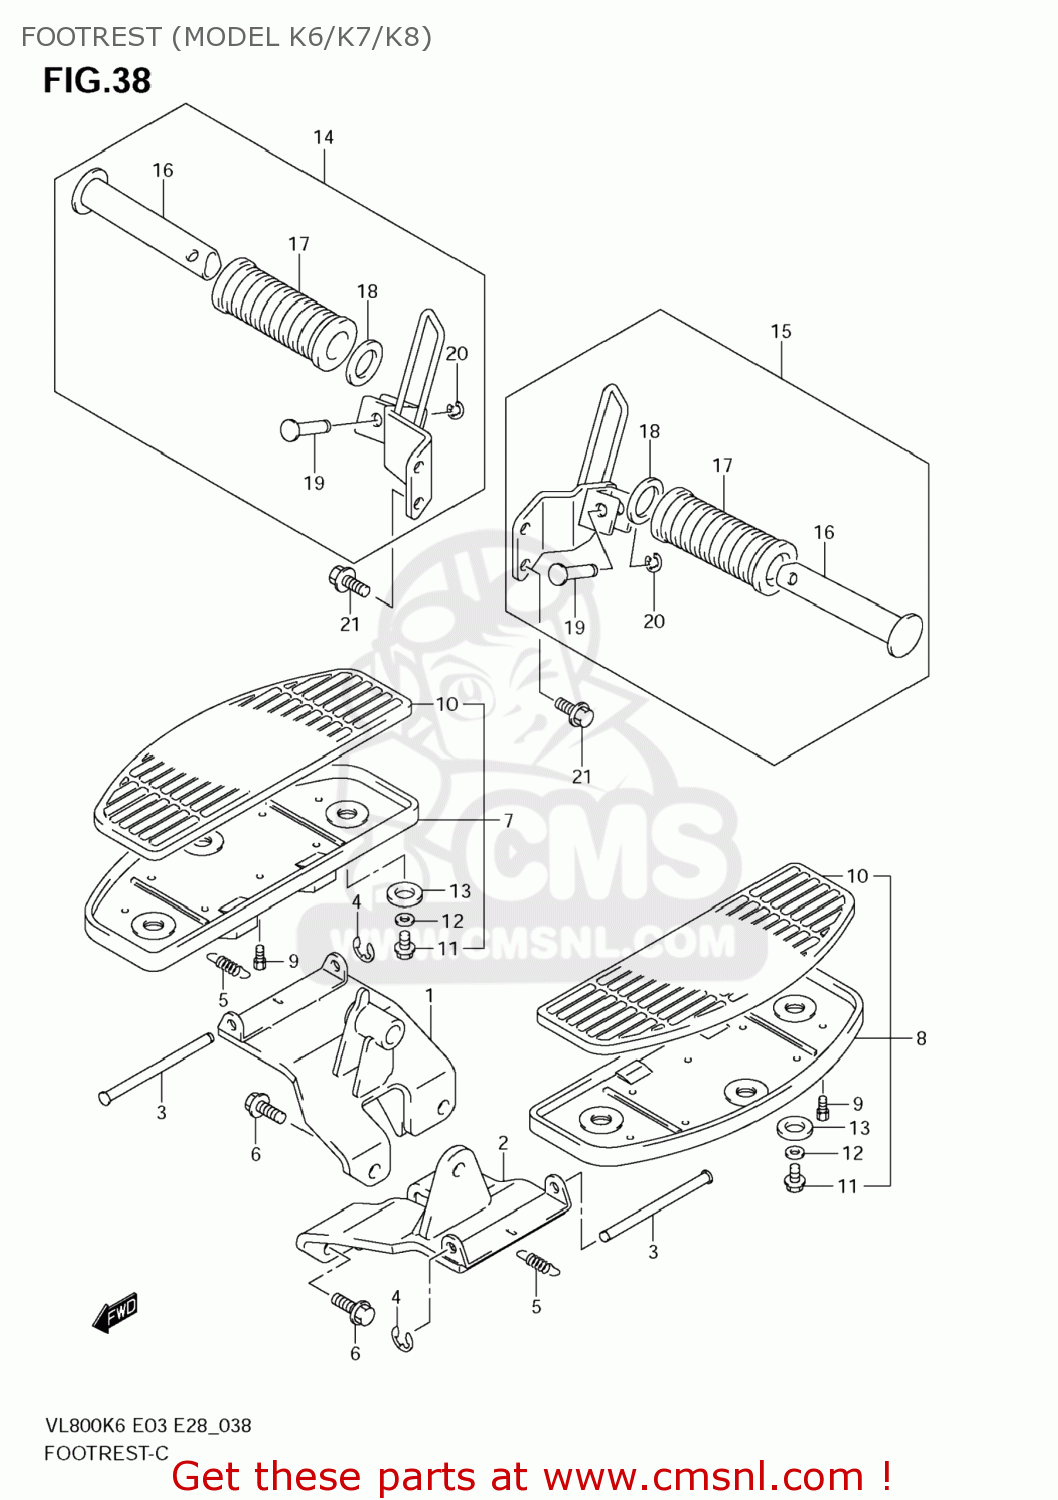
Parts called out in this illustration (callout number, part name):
1	BRACKET COMP,F
2	BRACKET COMP,F
3	PIN,FR FOOTREST
4	E RING
5	SPRING
6	BOLT
7	FOOTREST ASSY,FR,R
8	FOOTREST ASSY,FR,L
9	BOLT,BANK SENSOR
10	RUBBER,FR FOOTREST
11	BOLT
12	WASHER (6.5X22X1.6)
13	CUSHION
14	FOOTREST ASSY,PILLION,R
15	FOOTREST ASSY,PILLION,L
16	BAR,PILLION FOOTREST
17	RUBBER,PILLION FOOTREST
18	WASHER(19.5X32X2)
19	PIN,PILLION FOOTREST
20	E RING
21	BOLT(8X16)
